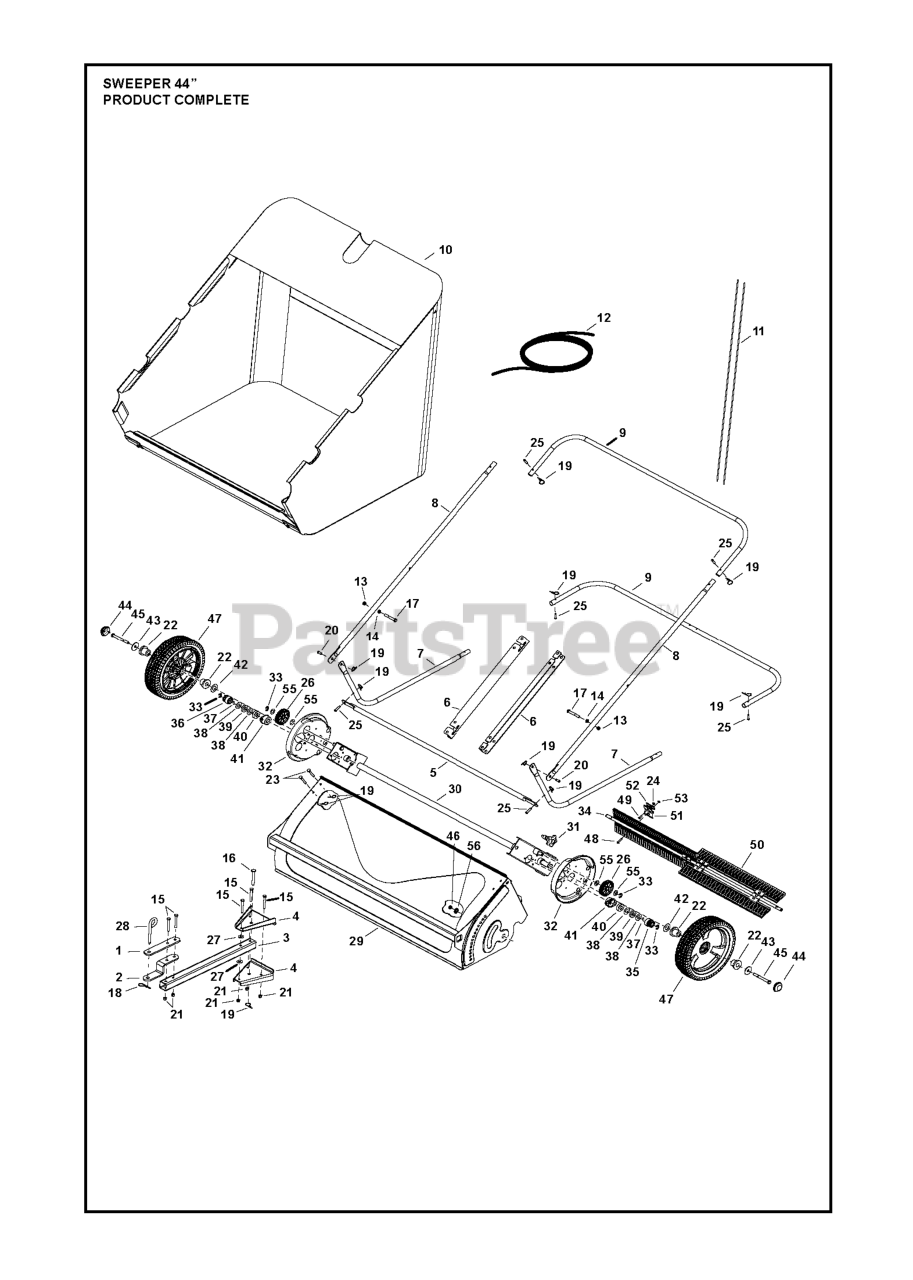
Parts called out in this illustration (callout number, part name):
2	HITCH BRACKET
19	Pin, Hair Cotter 3/32" #3
27	WASHER 47605
28	Pin, Hitch
32	DUST COVER
40	BALL BEARING
42	Washer, Flat 1-1/8" x .78" x .025"
45	HEX BOLT
47	WHEEL ASSY
51	BRUSHRETAINER DOUBLE
52	BRUSH RETAINER SINGLE
55	Washer, 1/2" x 1" x .02"
